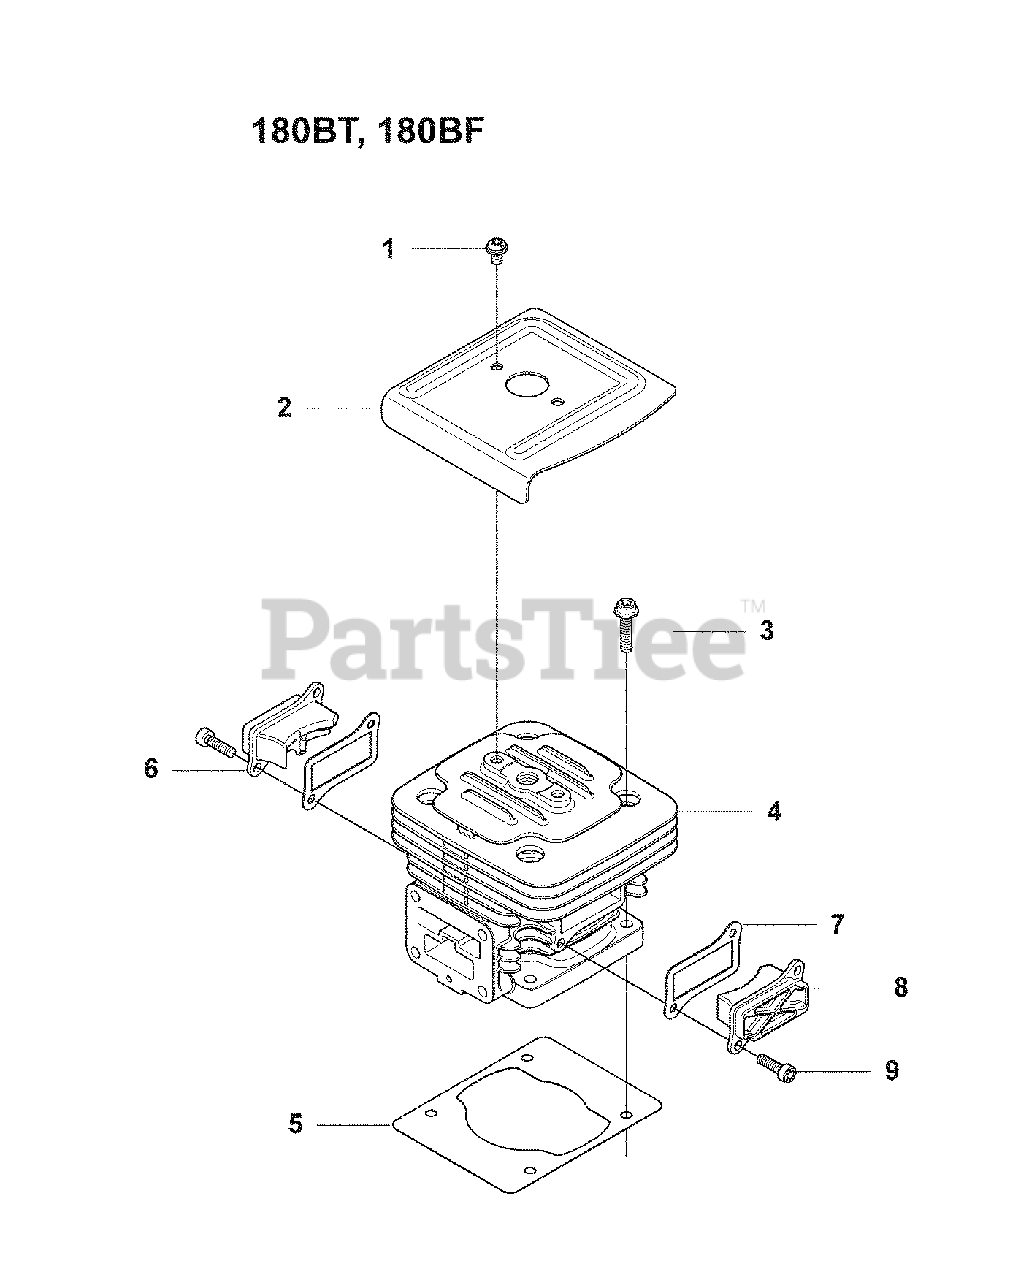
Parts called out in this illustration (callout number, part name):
3	Torx Bolt
5	Gasket
6	Cover, TR F
7	Gasket
9	Torx Bolt, M4 X L16
